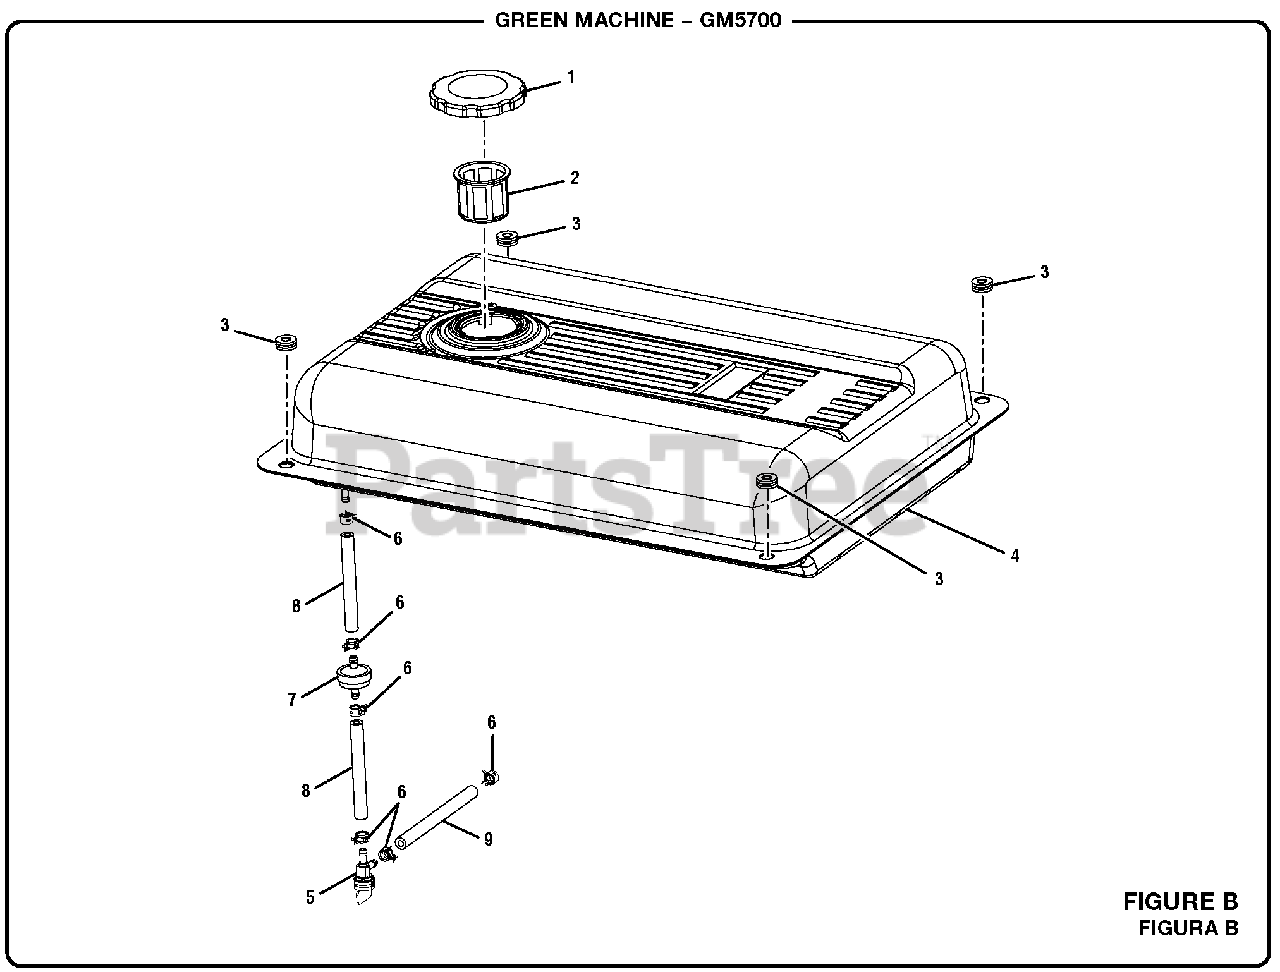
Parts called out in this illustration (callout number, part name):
1	Fuel Tank Cap
2	Fuel Tank Screen
3	Bushing w/Insert
4	Fuel Tank
5	Fuel Valve
6	Fuel Line Clamp (1/2 in.)
7	Fuel Line Filter
8	Fuel Line (1/4 in.)
9	Fuel Hose (5 mm)
